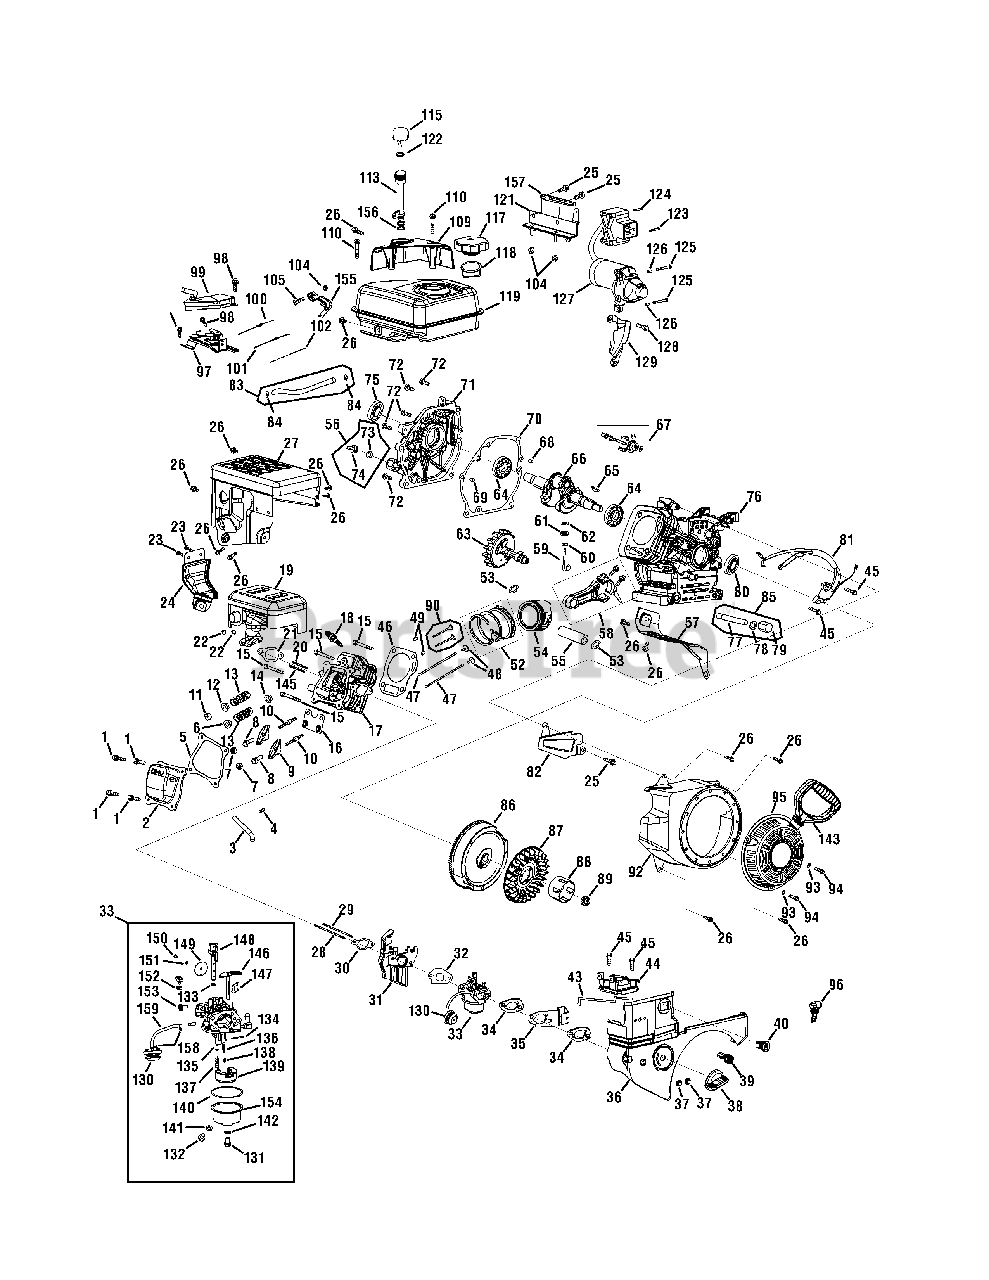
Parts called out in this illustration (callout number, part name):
2	Valve Cover
3	Breather Hose
4	Hose Clamp
5	Head Cover Gasket
6	Intake Valve Spring Seat
7	Pivot Locking Nut
8	Valve Adjusting Nut
9	Rocker Arm
10	Pivot Bolt
11	Exhaust Valve Adjuster
12	Exhaust Valve Spring Seat
13	Valve Spring
14	Intake Valve Seal
16	Push Rod Guide Plate
17	Cylinder Head - Complete
18	Spark Plug
19	Muffler Assembly
20	Stud
21	Muffler Gasket
24	Exhaust Pipe Shield
27	Muffler Shroud
28	Stud, M6 x117
29	Stud, M6 x 105
30	Carburetor Insulator Gasket
31	Carburetor Insulator Plate
32	Carburetor Gasket
33	Carburetor Assembly
34	Carburetor Gasket Plate
35	Choke Control Bracket
36	Engine Shroud
38	Choke Knob
39	Throttle Control Knob
40	Ignition Switch
43	Choke Push Rod
44	Heater Box
46	Cylinder Head Gasket
47	Push Rod Kit (incl. intake and exhaust rod)
48	Tappet
49	Dowel Pin
52	Piston Ring Set
53	Piston Pin Snap Ring
54	Piston
55	Piston Pin
56	Oil FIll Plug Assembly
57	Air Shield
58	Connecting Rod Assembly
59	Governor Arm Shaft
60	Washer
61	Governor Seal
62	Cotter Pin
63	Camshaft Assembly
64	Radial Ball Bearing
65	Flywheel Key
66	Crankshaft Assembly
67	Governor Gear/Shaft Assembly
68	Dowel Pin, 7 x 14
69	Dowel Pin, 9 x 14
70	Crankcase Cover Gasket
70	Crankcase Gasket
71	Case Cover
72	Bolt
72	Cover Bolts
73	O-Ring
74	Oil FIll Plug
74	Oil Fill Plug
75	Oil Seal
76	Crankcase
77	Oil Drain Pipe
78	Washer
79	Oil Drain Plug
80	Oil Seal
81	Ignition Coil
82	Air Flow Shield
83	Fuel Line Kit (incl. clamps and fuel line)
84	Hose Clamp
85	Oil Drain Assembly, includes 77, 78, 79
86	Flywheel
87	Cooling Fan
88	Starter Cup
89	Nut
90	Valve Kit (incl. intake and exhaust valve)
90	Valve Kit
92	Blower Housing
93	Washer
95	Recoil Starter Assembly
96	Key
97	Throttle Control Assembly
99	Governor Shield
100	Governor Spring
101	Throttle Return Spring
102	Governor Rod
104	Nut
109	Engine/Dipstick Cover
113	Dipstick Tube
115	Dipstick
117	Fuel Cap Assembly
118	Fuel Level Indicator
119	Fuel Tank
121	Switch Housing Mounting Bracket
122	O-Ring
123	Bolt, M4 x 55
124	Bolt, M4 x 60
126	Dowel Pin
127	Electric Starter
129	Blower Housing Shield
130	Primer
131	Bolt
132	Drain Bolt
133	Gasket, Throttle Plate
134	Float Pin
135	Emulsion Tube
136	Needle Valve
137	Main Jet
138	Needle Valve Spring
139	Float
140	Fuel Bowl Gasket
141	Fuel Drain Plug Gasket
142	Fuel Bowl Gasket
143	Starter Handle
145	Muffler Stud Assembly
146	Choke Shaft
147	Choke Plate
148	Throttle Shaft
149	Throttle Plate
150	Screw, M3×5
151	Lock Washer
152	Idle Jet Assembly
153	Idle Speed Adjusting Screw
154	Fuel Bowl
155	Governor Arm Bracket
156	O-Ring
157	Wire Clip
158	Hose Clamp
159	Primer Hose
